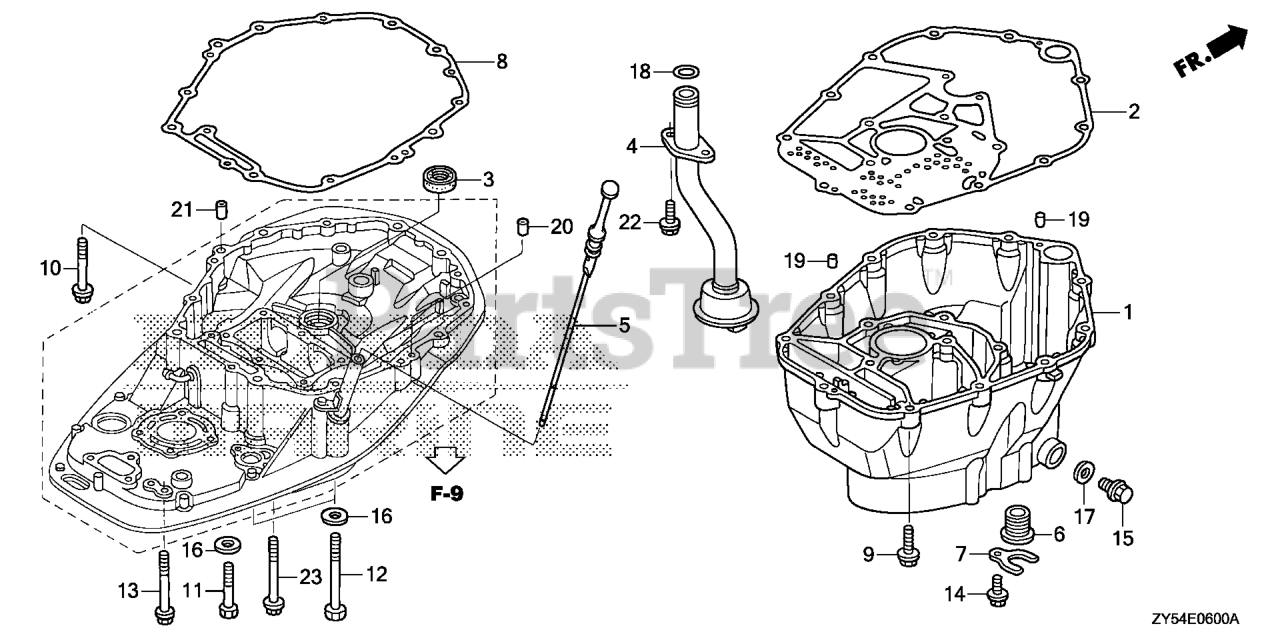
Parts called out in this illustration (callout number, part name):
1	CASE, OIL *TGRAY* (GRAY)
2	GASKET, OIL PAN
3	RUBBER, OIL PUMP
4	STRAINER, OIL
5	DIPSTICK, OIL
6	GROMMET, WATER TUBE
7	PLATE, WATER TUBE
8	GASKET, MOUNT CASE
9	BOLT, FLANGE (10X40)
10	BOLT, FLANGE (10X80)
11	BOLT, HEX. (12X70)
12	BOLT, HEX. (12X130)
13	BOLT, FLANGE (8X100)
14	BOLT, FLANGE (6X12) Use from Frame SN 1005249.
15	BOLT, DRAIN PLUG
16	WASHER, PLAIN (12MM)
17	WASHER, DRAIN PLUG (12MM)
18	O-RING (20.6X2.6)
19	PIN A, DOWEL (6X10)
20	PIN A, DOWEL (10X16)
21	PIN A, DOWEL (14X20)
22	BOLT, FLANGE (6X18)
23	BOLT, FLANGE (10X110)
